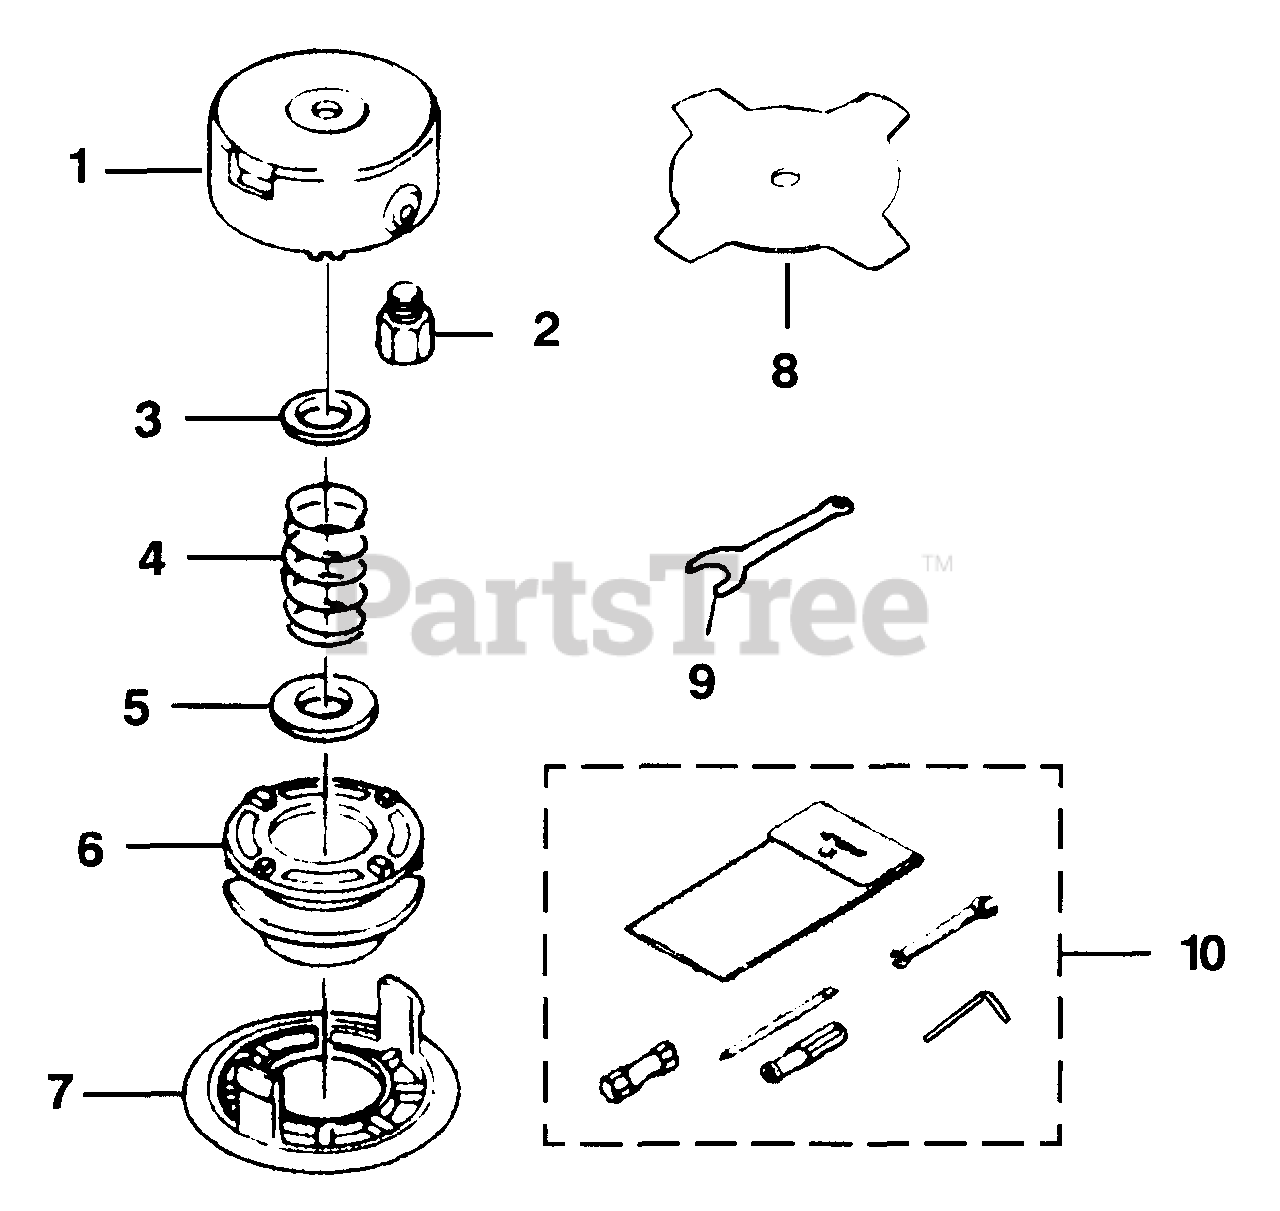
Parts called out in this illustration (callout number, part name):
1	6" Head Body
2	Arbor Bolt
3	Spring Plate
4	Spring
5	Plate, Spring
7	6" Cap
8	Quad Blade
9	Spanner Wrench
